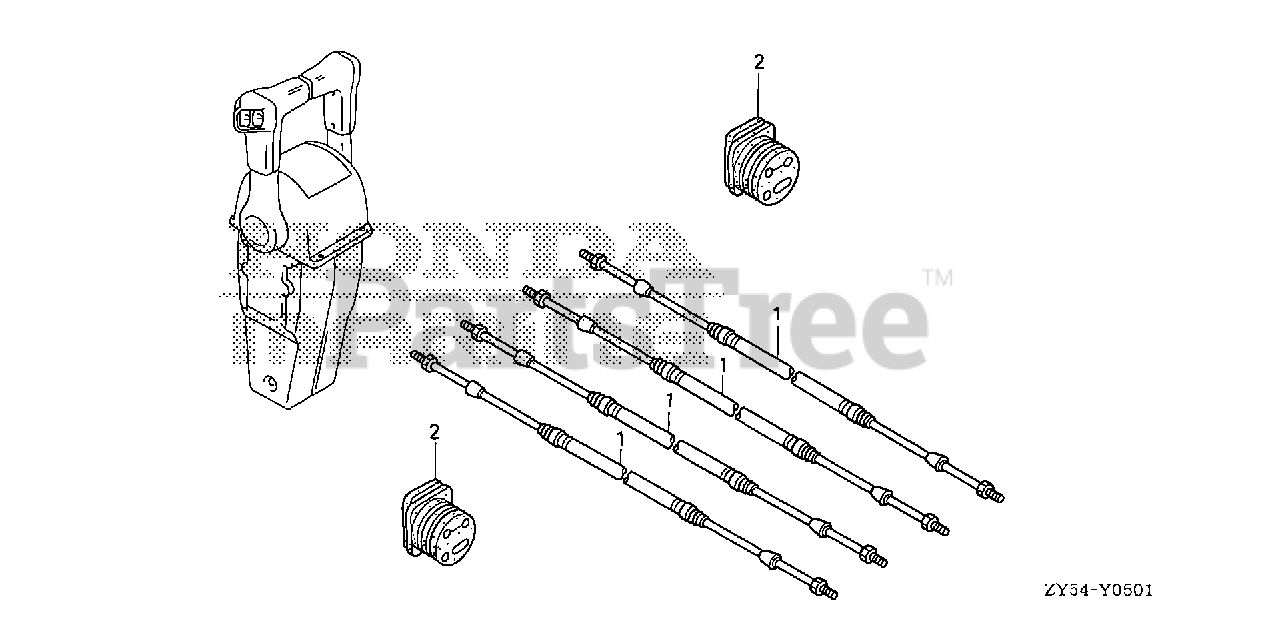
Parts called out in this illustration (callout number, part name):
1	CABLE ASSY., PUSH-PULL (33C-5FT)
1	CABLE ASSY., PUSH-PULL (33C-6FT)
1	CABLE ASSY., PUSH-PULL (33C-7FT)
1	CABLE ASSY., PUSH-PULL (33C-8FT)
1	CABLE ASSY., PUSH-PULL (33C-9F T)
1	CABLE ASSY., PUSH-PULL (33C-10FT)
1	CABLE ASSY., PUSH-PULL (33C-11FT)
1	CABLE ASSY., PUSH-PULL (33C-12 FT)
1	CABLE ASSY., PUSH-PULL (33C-13 FT)
1	CABLE ASSY., PUSH-PULL (33C-14FT)
1	CABLE ASSY., PUSH-PULL (33C-15 FT)
1	CABLE ASSY., PUSH-PULL (33C-16FT)
1	CABLE ASSY., PUSH-PULL (33C-17 FT)
1	CABLE ASSY., PUSH-PULL (33C-18 FT)
1	CABLE ASSY., PUSH-PULL (33C-19FT)
1	CABLE ASSY., PUSH-PULL (33C-20FT)
1	CABLE ASSY., PUSH-PULL (33C-21FT)
1	CABLE ASSY., PUSH-PULL (33C-22FT)
1	CABLE ASSY., PUSH-PULL (33C-23FT)
1	CABLE ASSY., PUSH-PULL (33C-24FT)
1	CABLE ASSY., PUSH-PULL (33C-25FT)
1	CABLE ASSY., PUSH-PULL (33C-26FT)
1	CABLE ASSY., PUSH-PULL (33C-27FT)
1	CABLE ASSY., PUSH-PULL (33C-28FT)
1	CABLE ASSY., PUSH-PULL (33C-29FT)
1	CABLE ASSY., PUSH-PULL (33C-30FT)
1	CABLE ASSY., PUSH-PULL (33C-31FT)
1	CABLE ASSY., PUSH-PULL (33C-32FT)
2	GROMMET, CASE (LOWER) (B)
